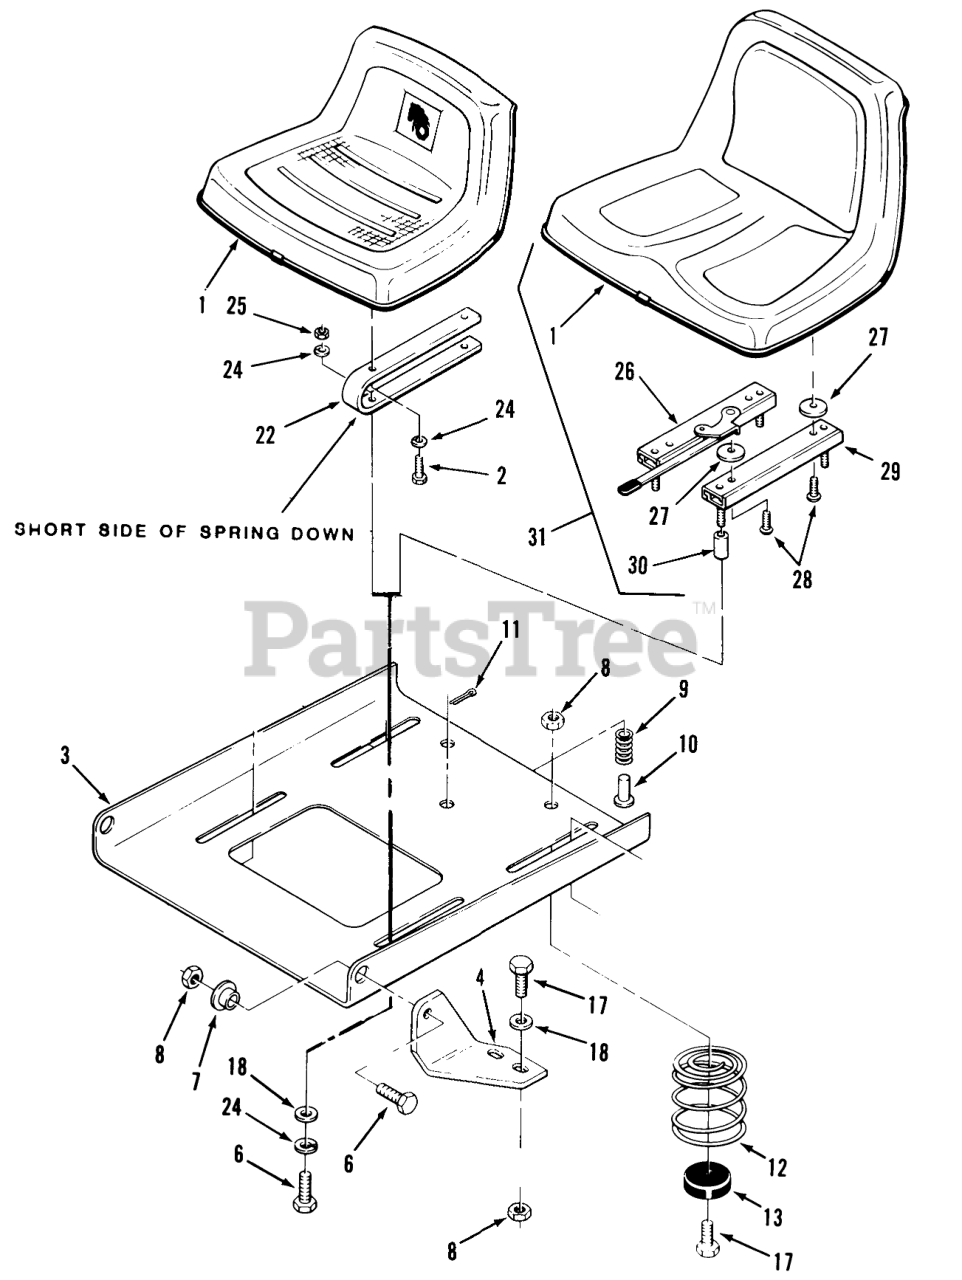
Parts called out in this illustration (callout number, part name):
1	Seat
2	Bolt
3	PLATE-SEAT PIVOT B
4	BRACKET-PIVOT L.H B
4	Bracket-Pivot RH
6	HHCS
7	BUSHING
8	Nut
9	SPRING-SEAT SWITCH
11	Cotter Pin
12	SPRING
12	SPRING-SEAT NYLON
13	BUMPER
17	Bolt
18	WASHER 5/16 SAE
22	Seat Spring
24	Lockwasher
25	Nut
26	ADJUSTER-SEAT RH
27	SPACER-NYLON
28	Screw
29	ADJUSTER-SEAT LH
30	SPACER
31	Deluxe Seat Assembly
